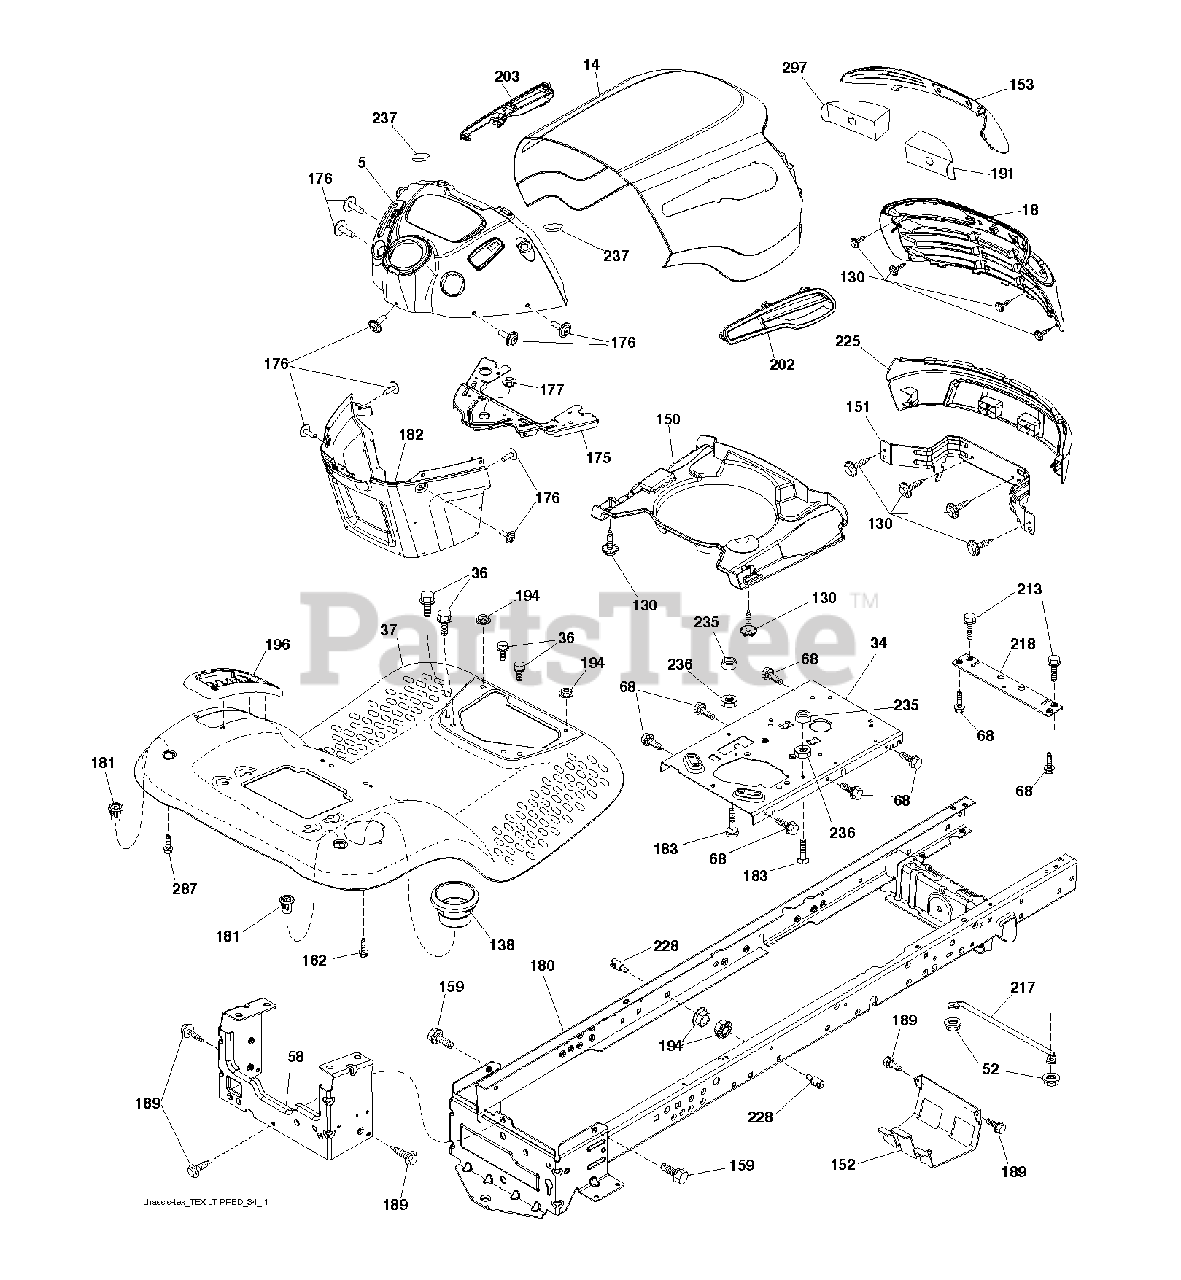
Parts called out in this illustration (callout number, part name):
34	PLATE.ENGINE.WELDED.CHASSIS
36	SCREW 5/16"
52	LOCKNUT
58	DRAWBAR UPPER 2PC SMALL FENDER
130	SCREW.#10 X 0.750.BOS THREAD
138	CUPHOLDER.TL.TEX.BLACK
151	BRACKET.PIVOT.ALPHA.LT
152	SHIELD BROWNING
159	SCREW, 3/8-16X3/4
162	SCREW.HI-LO.CONSOLE
175	CROSSMEMBER
176	SCREW.#10-24X5/8.RN.QU
177	BUSHING STEERING
180	CHASS.WLDMNT.TL.12GA/2P.48/54
181	FEND/FTRST.PCH.CPH.NFW
182	DASH.LWER.PREDATOR/HUSQ.LT
183	BOLT.5/16-18X1-1/4 FULL.THREAD
189	SCREW
191	INSERT.REFLECT.PREDATOR.LT.RH
194	NUT LOCK HEX FLANGE 5/16-18
196	CONSOLE.ASM.DECKLFT.BL/RBT.TLT
213	BOLT
217	ROD.PIVOT.HOOD
218	X-PIECE.HOOD.STOP.NON/
228	STUD.FASTNER.W/ANTI-ROTATE
235	SPACER FENDER
236	NUT.CENTERLOCK.5/16-
237	PLUG.MOUNT.CARGO.BLK
297	REFLECTOR.INSERT.PRED.LH.LT
